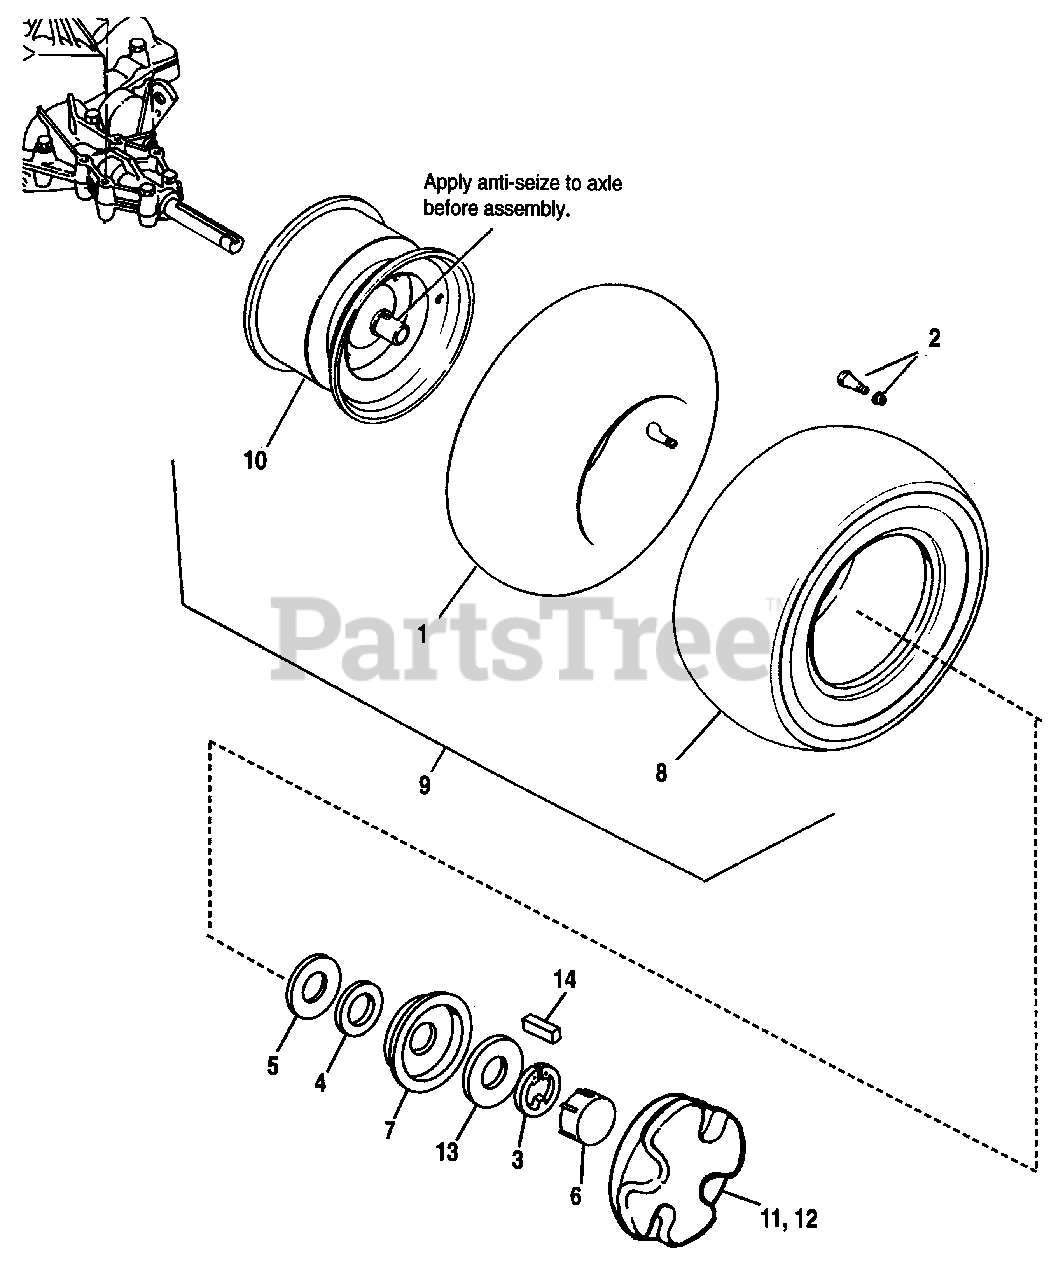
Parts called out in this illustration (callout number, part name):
1	TUBE, Rear Wheel
2	VALVE STEM & CAP
4	WASHER, 3/4 (Qty. 10 used on hydro models)
5	SPACER (Hydro models only)
6	CAP, Threaded
7	RETAINER, Cap
8	TIRE, Rear Wheel, 16 X 6.50-8
9	REAR WHEEL & TIRE ASSY. (Incl. Ref. Nos. 1, 2, 8 & 10)
10	REAR WHEEL ASSY., Metallic Gray
11	HUB CAP, Smooth, 8"
12	HUB CAP, Scalloped, 8"
13	WASHER, 3/4 I.D. x 1-1/16 O.D. x 1/16 Thk.
14	KEY, Square, 3/16 x 3/16 x 1-1/2 long
